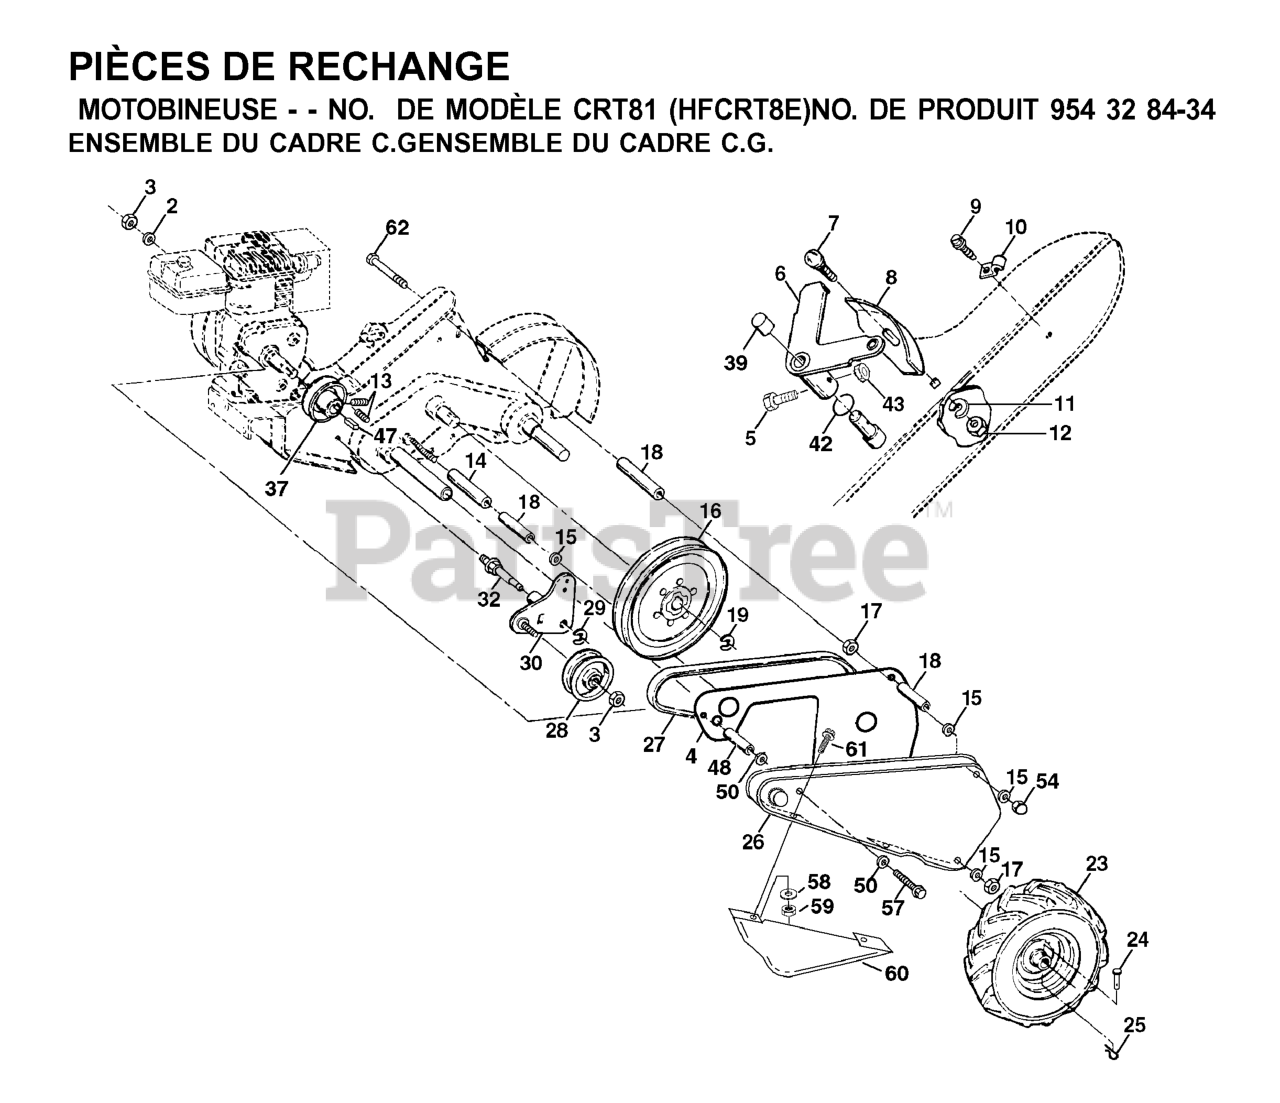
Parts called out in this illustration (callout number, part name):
2	WASHER, LOCK 3/8
3	NUT.HEX.3/8-16UNC
5	SCREW, SHIFT LEVER
6	LEVER ASM CRT
8	PANEL.INDICATOR.SHIFT.BLACK
9	TAPPING SCREW
10	CONDUIT.CLIP.PLATED
11	LOCKWASHER
12	NUT
14	SPACER-SPLIT.327 X .42
15	WASHER
16	SHEAVE, TRANSMISSION
18	SPACER SPLIT
19	RETAINING RING LT
23	TIRE.16X4-8.CHEVRON.TILLER
25	SPRING TI
27	BELT, DRIVE
28	PULLEY-IDLER TI
30	BRACKET.ASM.IDLER.BLACK
32	SHAFT, IDLER ARM
37	SHEAVE, ENGINE
39	CAP.PLUNGER.BLACK
47	KEY, SQUARE
50	WASHER
57	Bolt, Hex Head 1/2-20 x 2-3/4
58	WASHER, .196 X .625 X 16 GA
59	NUT **
61	SCREW.PNHD.10-24
62	BOLT 5/16-18X4 1/2
532124366	RIM
532124718	VALVE STEM LT
